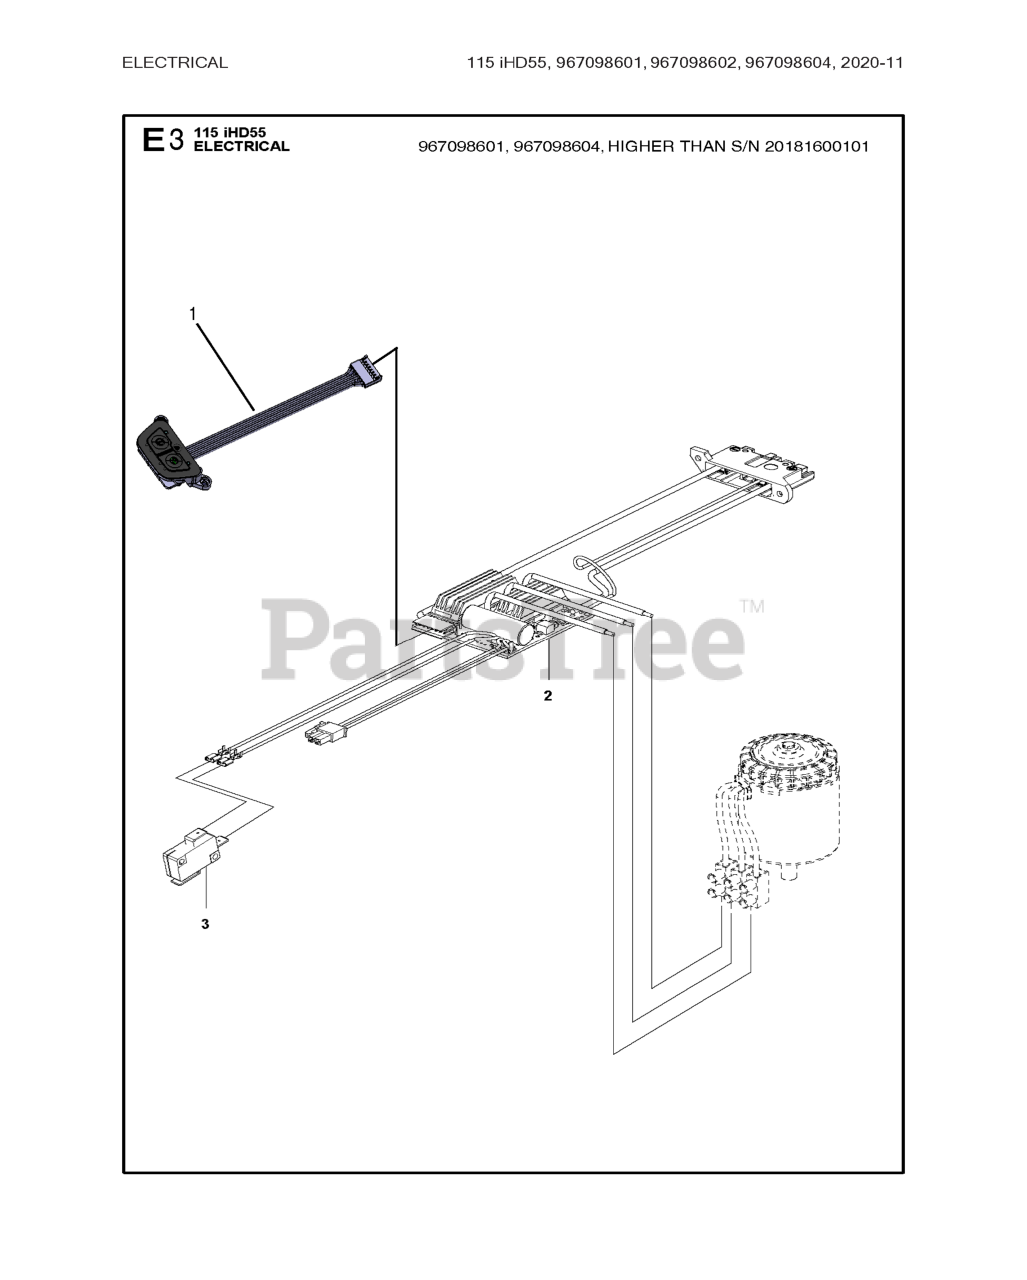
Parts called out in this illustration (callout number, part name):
1	KEYPAD ASSEMBLY
2	Controls
3	MICRO SWITCH
